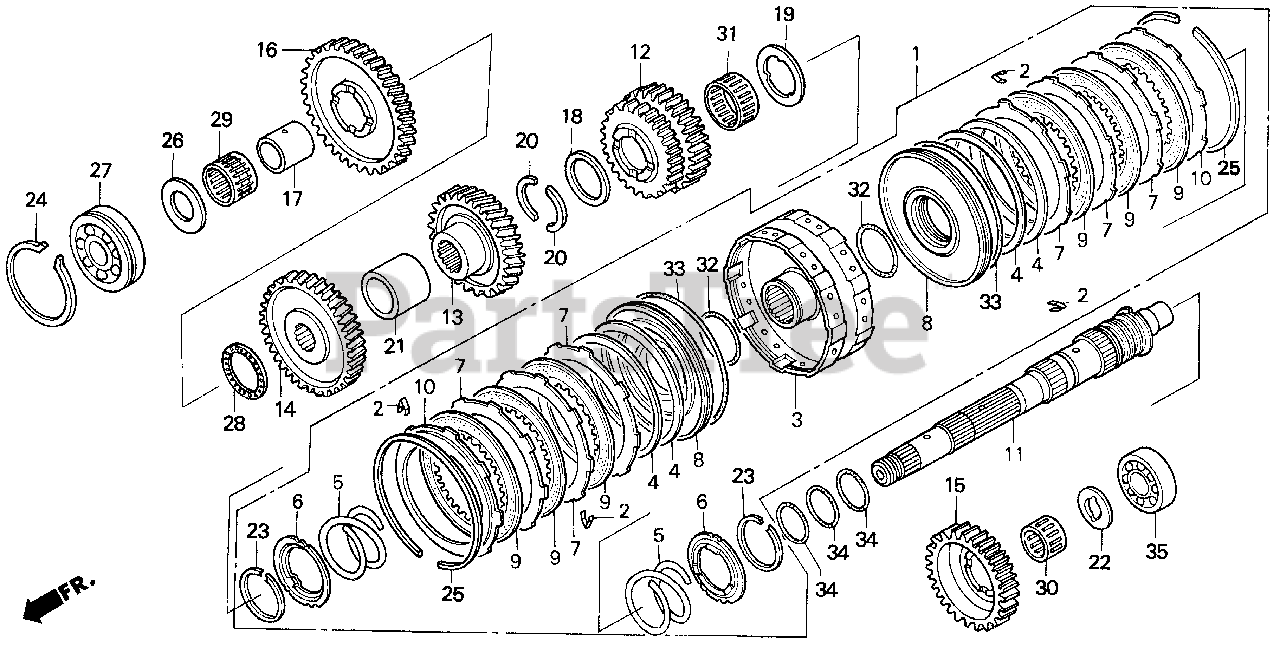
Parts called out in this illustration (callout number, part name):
1	CLUTCH ASSY., FIRST & REVERSE
2	SPRING, DISK SETTING
3	GUIDE, FIRST & REVERSE CLUTCH
4	SPRING, CLUTCH DISK
5	SPRING, CLUTCH RETURN
6	SEAT, CLUTCH SPRING
7	PLATE, CLUTCH (106)
8	PISTON, CLUTCH
9	DISK, CLUTCH
10	PLATE, CLUTCH END (2.3MM)
10	PLATE, CLUTCH END (2.6MM)
10	PLATE, CLUTCH END (2.9MM)
10	PLATE, CLUTCH END (3.2MM)
10	PLATE, CLUTCH END (3.5MM)
10	PLATE, CLUTCH END (2.15MM)
10	PLATE, CLUTCH END (2.45MM)
10	PLATE, CLUTCH END (2.75MM)
10	PLATE, CLUTCH END (3.05MM)
10	PLATE, CLUTCH END (3.35MM)
10	PLATE, CLUTCH END (3.65MM)
12	GEAR, FIRST DRIVE (28/38T)
13	GEAR, SECOND DRIVE (33T)
14	GEAR, THIRD DRIVE (38T)
15	GEAR, REVERSE DRIVE (16T-38T)
16	GEAR, P.T.O. IDLE (41T-24T)
17	COLLAR (26X32X27)
18	WASHER A, THRUST (32MM) (-0.02/-0.05) (NOT AVAILABLE)
19	WASHER, SPLINE (35X50X3.00)
19	WASHER, SPLINE (35X50X3.05)
19	WASHER, SPLINE (35X50X3.10)
19	WASHER, SPLINE (35X50X3.15)
19	WASHER, SPLINE (35X50X3.20)
19	WASHER, SPLINE (35X50X3.25)
19	WASHER, SPLINE (35X50X3.30)
19	WASHER, SPLINE (35X50X3.35)
19	WASHER, SPLINE (35X50X3.40)
20	COTTER (28MM)
21	COLLAR, DISTANCE (28X38X34)
21	COLLAR, DISTANCE (28X38X34.05)
21	COLLAR, DISTANCE (28X38X34.10)
21	COLLAR, DISTANCE (28X38X34.15)
21	COLLAR, DISTANCE (28X38X34.20)
21	COLLAR, DISTANCE (28X38X34.25)
21	COLLAR, DISTANCE (28X38X34.30)
21	COLLAR, DISTANCE (28X38X33.90)
21	COLLAR, DISTANCE (28X38X33.95)
22	SHIM B, FINAL SHAFT (2.0MM)
23	CIRCLIP (OUTER) (40MM) (F.C.C.)
24	RING, SNAP (62MM)
25	RING, SNAP (114X1.8)
26	WASHER, THRUST (25X45X3.8)
26	WASHER, THRUST (25X45X3.9)
26	WASHER, THRUST (25X45X4.0)
26	WASHER, THRUST (25X45X4.1)
26	WASHER, THRUST (25X45X4.2)
26	WASHER, THRUST (25X45X4.3)
26	WASHER, THRUST (25X45X4.4)
26	WASHER, THRUST (25X45X4.5)
26	WASHER, THRUST (25X45X4.6)
26	WASHER, THRUST (25X45X4.7)
26	WASHER, THRUST (25X45X4.8)
26	WASHER, THRUST (25X45X4.9)
27	BEARING, BALL (6305) (TOYO)
28	NEEDLE, THRUST (32X44X2)
29	BEARING, NEEDLE (32MM) (TOMUSON)
30	BEARING, NEEDLE (22X27X20)
31	BEARING, NEEDLE (32X37X18)
32	O-RING (39.8X2.2) (ARAI)
33	O-RING (100X2.2) (NOK)
34	O-RING (31.2X1.9) (ARAI)
35	BEARING, RADIAL BALL (6204)
